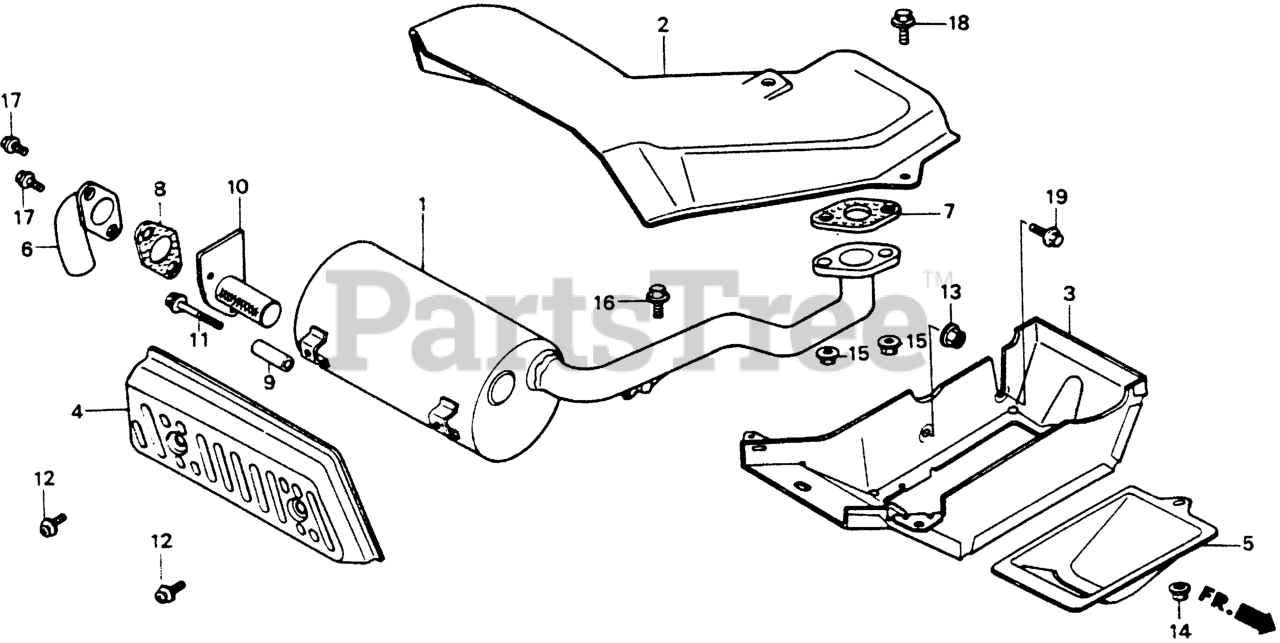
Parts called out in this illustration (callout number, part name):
1	MUFFLER (NOT AVAILABLE)
2	PROTECTOR, HEAT (UPPER)
3	PROTECTOR, HEAT (LOWER)
4	PROTECTOR, MUFFLER
5	COVER, PROTECTOR (LOWER) (NOT AVAILABLE)
6	PIPE, TAIL
7	GASKET, EX. PIPE Use up to Engine SN 2949254.
7	GASKET, EX. PIPE (WACKER)
8	GASKET, TAIL PIPE
9	COLLAR, MUFFLER JOINT
10	ARRESTER, SPARK (NOT AVAILABLE)
11	BOLT, FLANGE (8X55)
12	SCREW-WASHER (6X10)
13	NUT, FLANGE (6MM)
14	NUT, FLANGE (6MM)
15	NUT, FLANGE (8MM)
16	BOLT, FLANGE (6X10)
17	BOLT, FLANGE (6X10)
18	BOLT, FLANGE (6X12) Use from Engine SN 2086984.
19	BOLT, FLANGE (6X16)
